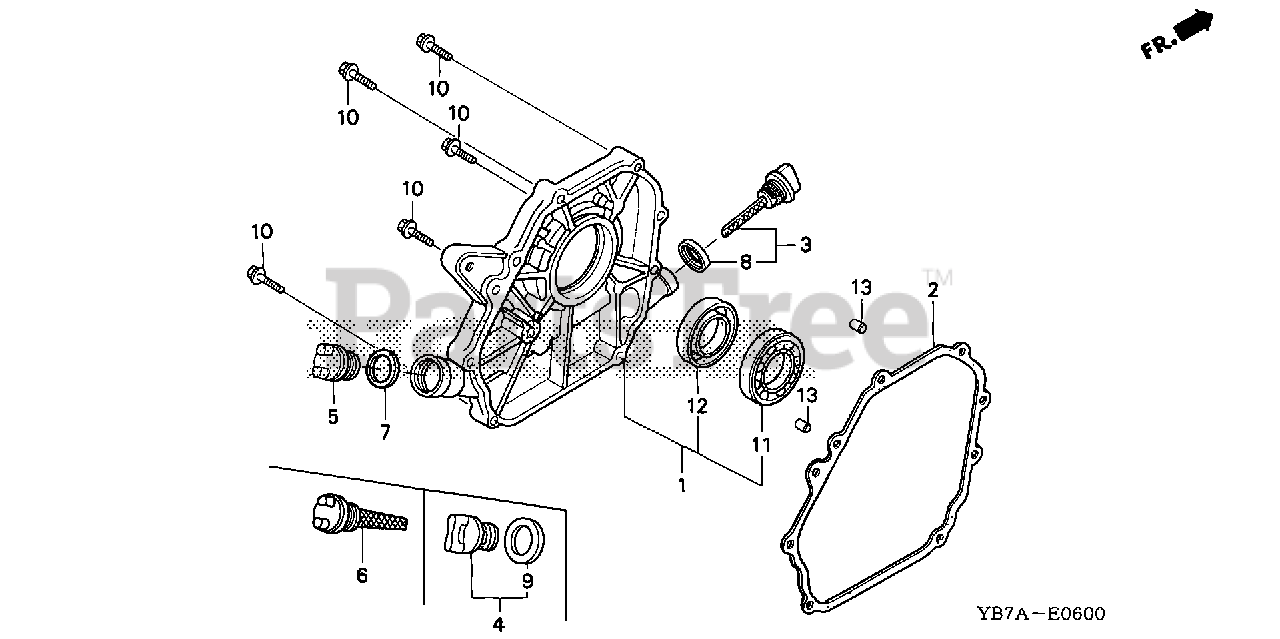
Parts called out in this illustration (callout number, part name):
1	COVER ASSY., CRANKCASE
2	GASKET, CASE COVER (NON-ASBESTOS)
3	CAP ASSY., OIL FILLER (GRAY)
4	CAP ASSY., OIL FILLER
8	GASKET, OIL FILLER CAP
9	GASKET, OIL FILLER CAP
10	BOLT, FLANGE (8X32)
11	BEARING, RADIAL BALL (6205)
12	OIL SEAL (25X41X6) (NOK)
13	PIN, DOWEL (8X14)
